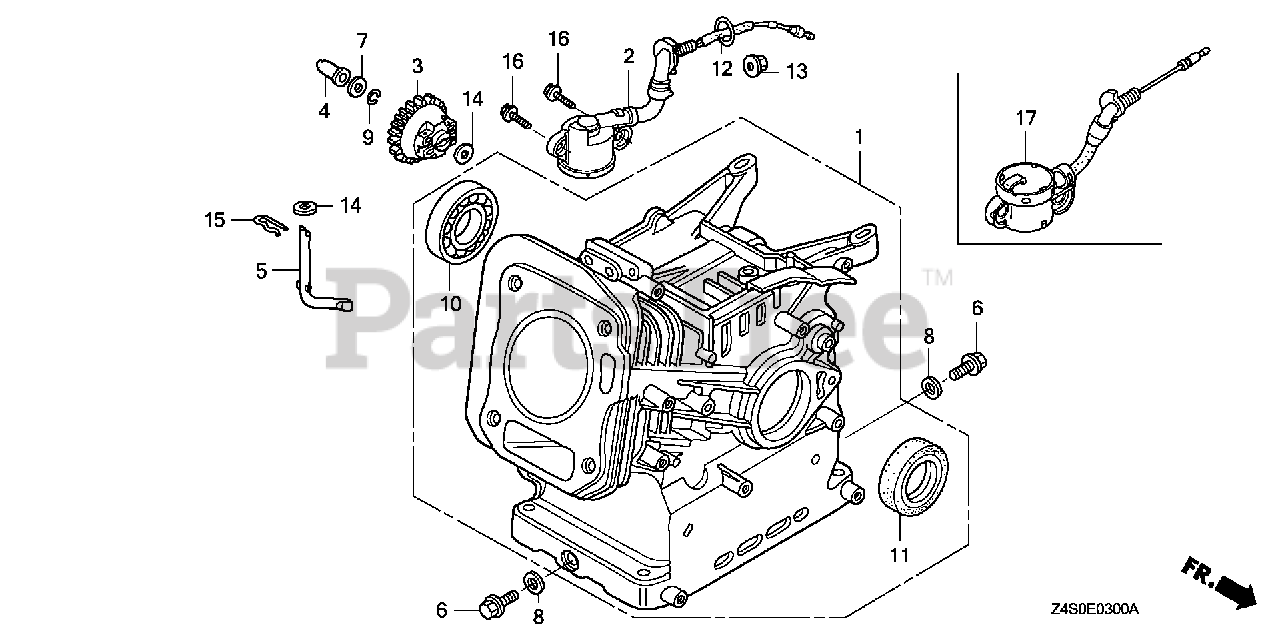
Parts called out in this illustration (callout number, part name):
1	CYLINDER ASSY.
2	SWITCH ASSY., OIL LEVEL
3	GOVERNOR ASSY.
4	SLIDER, GOVERNOR
5	SHAFT, GOVERNOR ARM
6	BOLT, DRAIN PLUG
7	WASHER, THRUST (6MM)
8	WASHER, DRAIN PLUG (10.2MM)
9	CLIP, GOVERNOR HOLDER
10	BEARING, RADIAL BALL (6205)
11	OIL SEAL (25X41X6)
12	O-RING (14MM) (ARAI) Use up to Engine SN 2949254.
12	O-RING (14MM) (NOK)
13	NUT, FLANGE (10MM)
14	WASHER, PLAIN (6MM)
15	PIN, LOCK (8MM)
16	BOLT, FLANGE (6X12) Use up to Engine SN 1543277.
